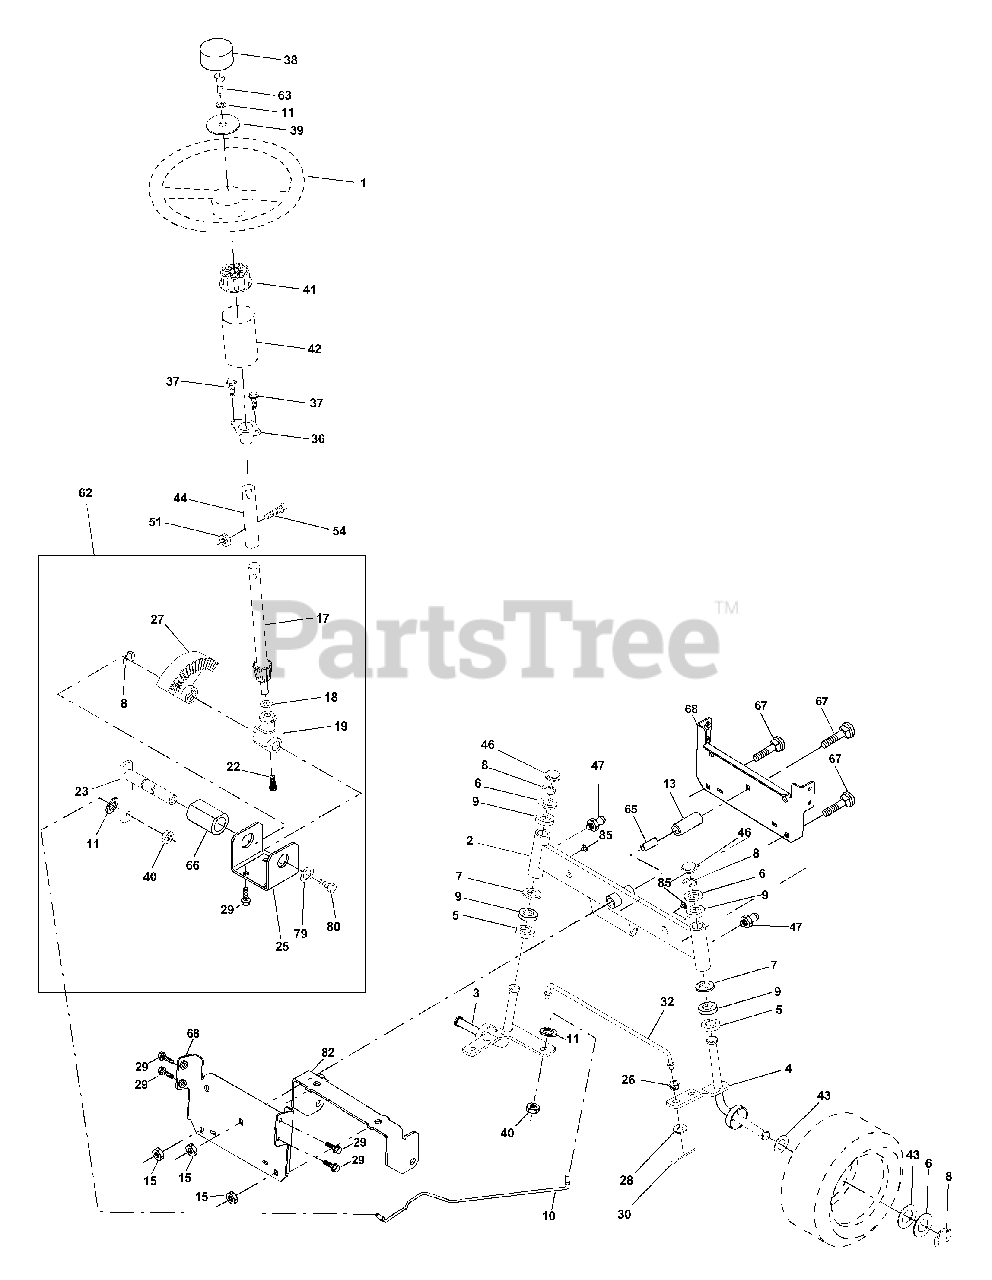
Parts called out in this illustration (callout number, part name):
1	Wheel Steering
2	Axle Asm Cast Iron LT
3	Spindle Asm LH
4	Spindle Asm RH
5	Bearing Race Thrust Harden
6	Washer 25/32 X 1-5/8 X 16 Ga
8	Ring Klip #t5304-75
10	Link Drag
11	Washer Lock Hvy Hlcl Spr 3/8
13	Spacer Brg Axle Front
15	Nut Hex Flange Lock
17	Shaft Asm Strg
18	Washer Thrust 515x 750x 033
19	Support Shaft
22	Screw Hex Wsh Hd Torx
23	Shaft Asm Pittman
25	Bracket Steering
27	Gear Sector
29	Screw 3/8-16 x .75
32	Rod Tie
33	Washer 11/32 x 3/4 x 16 Ga
34	Washer Lock Hvy Hlcl Spr 5/16
35	Crownlock Nut 5/16-24 Unf
36	Bushing Strg
37	Screw
38	Insert Cap Strg Wh
39	Washer 13/32 X 1-1/2 X 11 Ga
40	Lock nut
41	Adaptor Wheel Strg
42	Boot Steering Dash
43	Washer 25/32 X 1 1/4 X 16 Ga
44	Extension Steering Shaft LR/LT
46	Cap Spindle Fr Top Blk
47	Fitting Grease
51	Nut Lock Hex w/Ins 5/16-18
54	Bolt Fin Hex 5/16-18 Unc x 1-1/4
62	Kit, Steering Assembly Svc
63	Bolt Fin Hex 3/8-16unc x 1 Gr. 5
65	Spacer Brace Axle
66	Bearing Arm Pittman
67	Bolt Rdhd Sq 3/8-16 Unc x 2-3/4
68	Axle, Brace
79	Washer 13/32 x 1-1/4 x 12 Ga.
80	Bolt Hex Nylon 3/8-16 x 3/4
82	Bracket Susp Chassis Front
85	Fastner Christmas Tree
